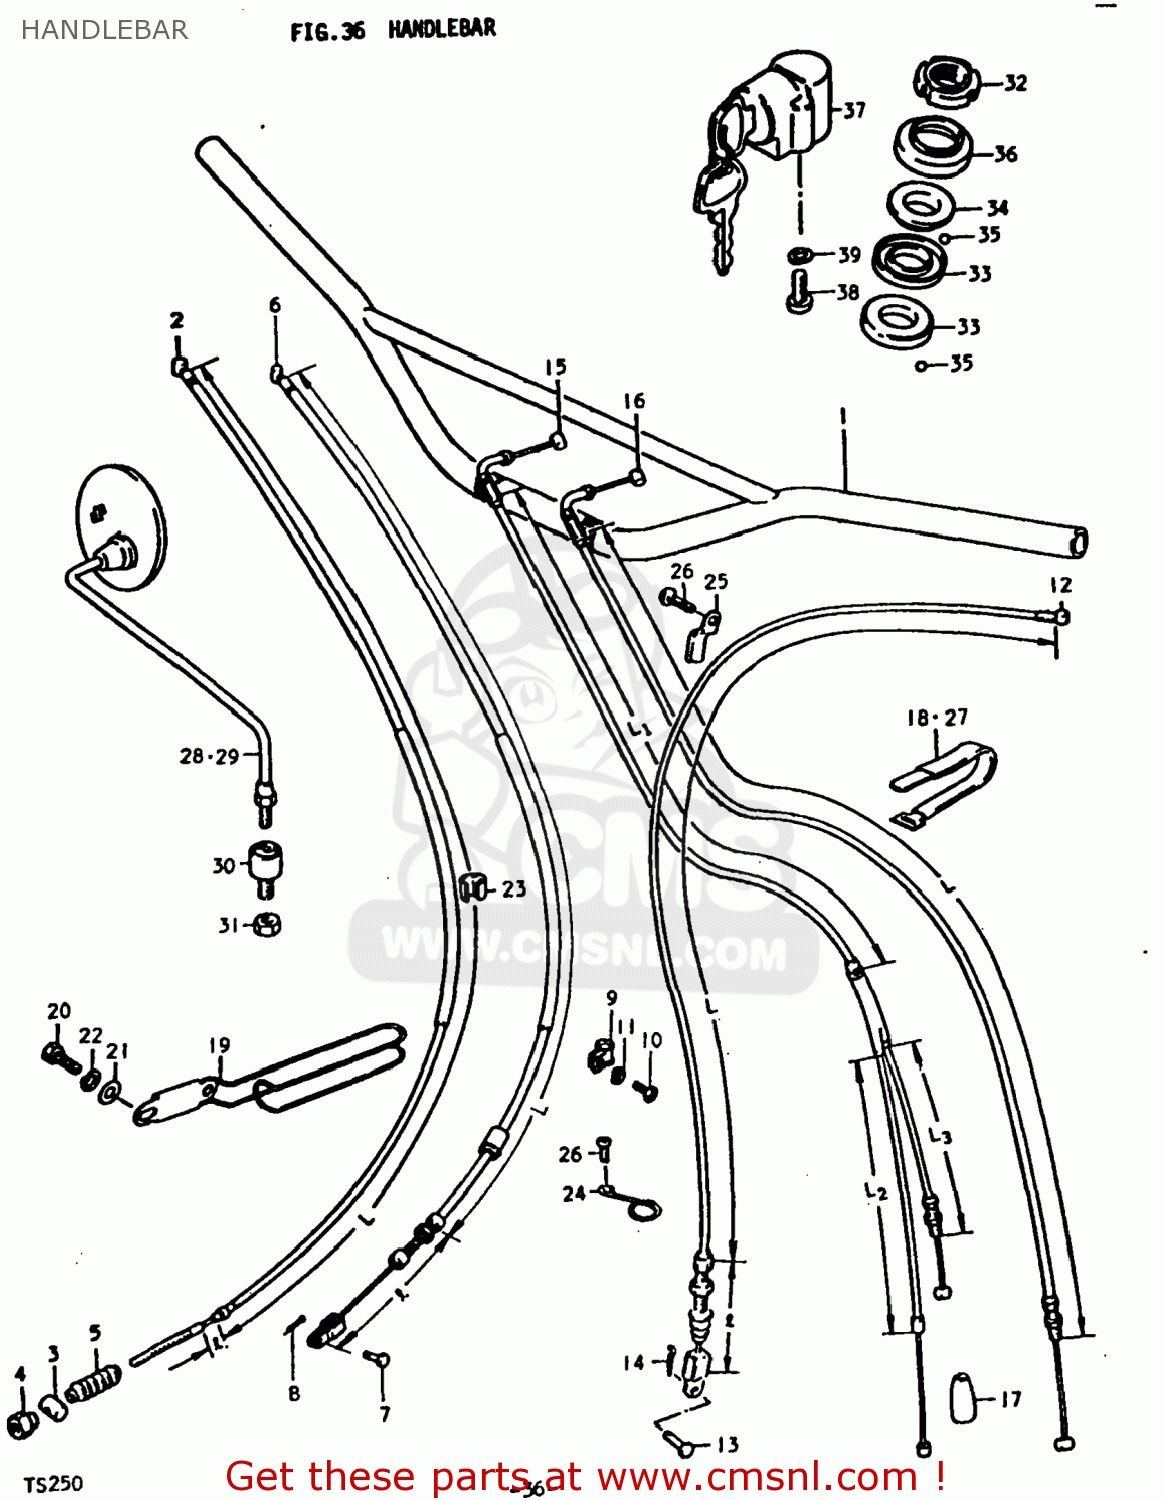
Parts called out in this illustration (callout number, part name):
1	HANDLEBAR
2	CABLE,FR BRAKE
3	PIN
4	NUT
5	SEAL,DUST
6	CABLE ASSEMBLY,FRONT BRAKE
7	PIN(L:17.5)
8	PIN
9	GUIDE,CABLE
10	SCREW
11	LOCK WASHER
12	CABLE ASSY,CLUTCH
13	PIN(L:15)
14	PIN
15	CABLE ASSEMBLY,THROTTLE
16	CABLE ASSEMBLY,THROTTLE
17	SEAL,DUST(7X18X30)
18	CLAMP
19	GUIDE,CABLE
20	BOLT 8X12
21	WASHER
22	LOCK WASHER
23	CLIP
24	CLIP
25	CLAMP
26	SCREW
27	CLAMP
28	MIRROR ASSEMBLY,RIGHT
29	MIRROR ASSEMBLY,LEFT
30	CUSHION,REAR VIEW MIRROR
31	NUT
32	NUT,STEERING STEM(25X44X10)
33	LACE,STEERING INNER LWR
34	LACE,STEERING OUTER UPR
35	BALL
36	DUST SEAL,STEERING UPR
37	LOCK ASSEMBLY,STEERING
38	SCREW
39	LOCK WASHER
